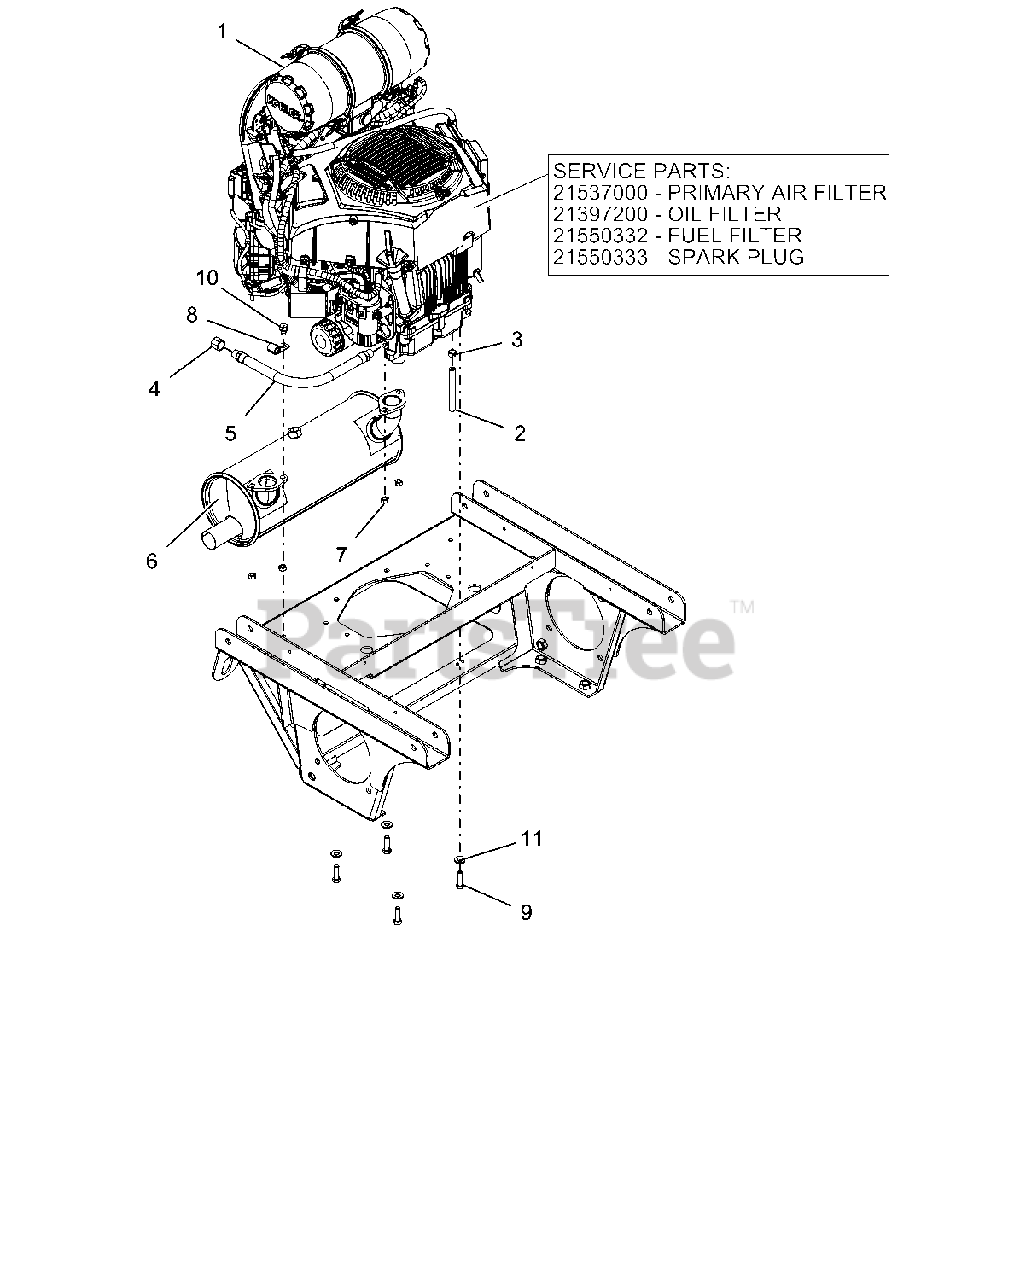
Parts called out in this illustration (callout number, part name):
1	ENGINE, KOHLER EFI
1	PRIMARY AIR FILTER
1	OIL FILTER
1	FUEL FILTER
1	SPARK PLUG
2	.25 LOW-PERM GAS HOSE 19.0" LG - VALVE TO ENGINE
3	CLAMP, FUEL LINE
4	PIPE, CAP 3/8 NPT FEMALE
5	HOSE, HYD .38-11-OK M6N0-M6N0
6	MUFFLER, KOHLER EFI
7	NUT-LK-TOP M8-1.25 YWZC
9	BLT-HEX .38-16X1.25 GR5 YWZC NYTORQ
10	SCR-TAP .38-16X.50 HWH TR YWZ
11	WSHR, 3/8" SPRING DISC
